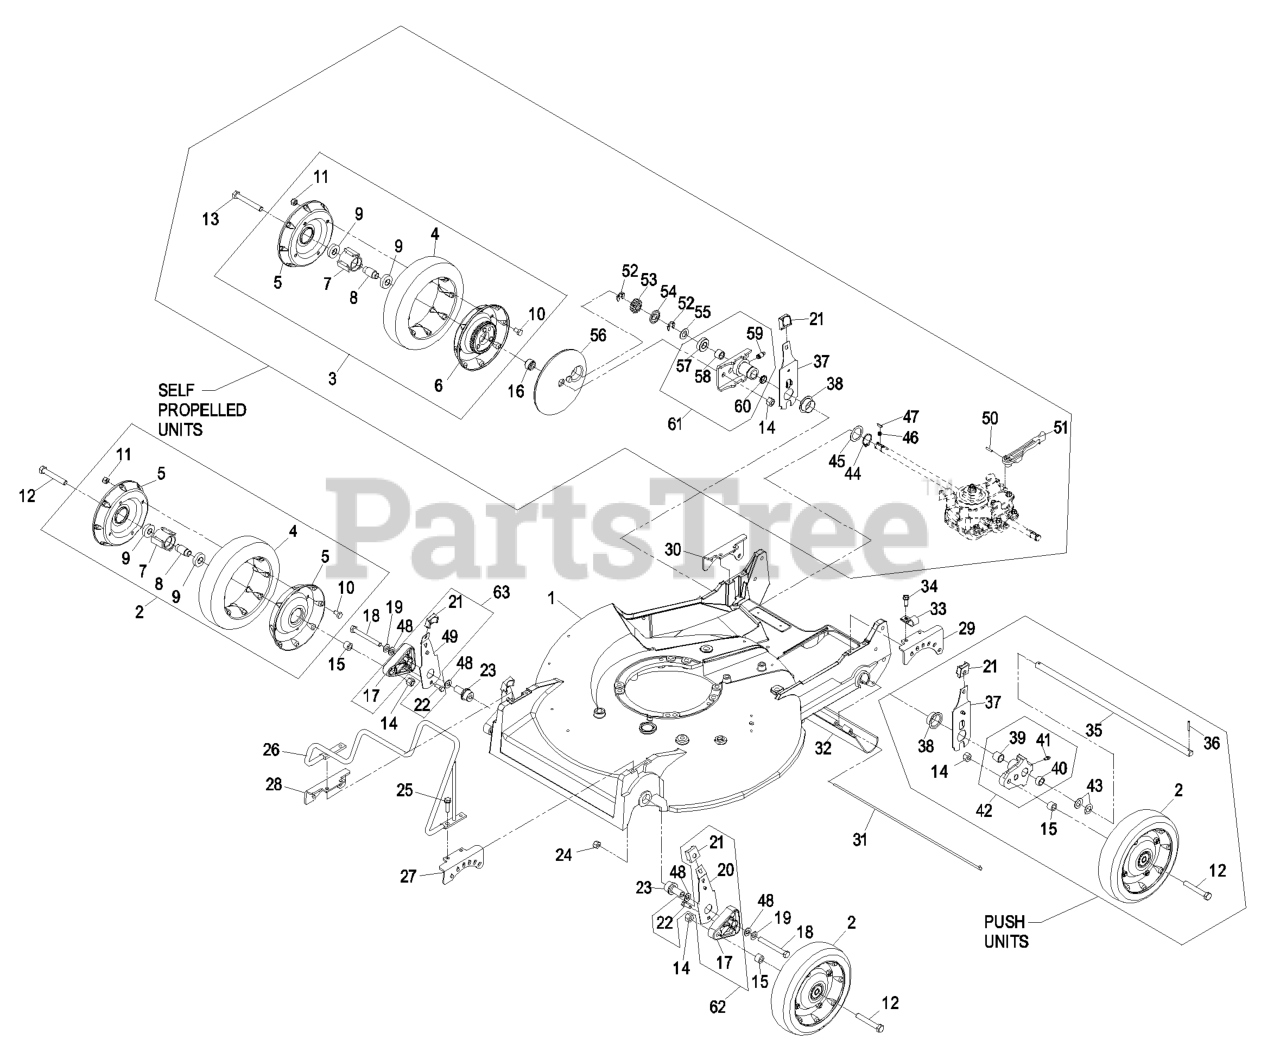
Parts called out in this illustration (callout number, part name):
7	HUB-BEARING
8	SPACER-BEARING
9	BEARING-WHEEL
10	SCREW-HH
11	NUT-LOCK, NI
12	BOLT-CARR
13	SCREW-HH
14	NUT-LOCK, CONE
15	SPACER-WHEEL
16	SPACER-COVER, WHEEL
17	ARM-PIVOT, FRONT
18	SCREW-HH
19	WASHER-FLAT
20	LH FRONT SPRING ARM ASM
21	KNOB-ARM
22	SCREW-HWHTF
23	BUSHING-PIVOT, WHEEL
24	NUT-LOCK, NI
25	SCREW-HWHTF
26	GUARD-ENGINE
27	BRACKET,QUADRANT FRONT LH
28	BRACKET,QUADRANT FRONT RH
29	BRACKET,QUADRANT REAR LH
30	BRACKET,QUADRANT REAR RH
31	ROD-SHIELD
32	SHIELD-TRAILING
33	CLIP-LOOM
34	SCREW-HWHTF
35	SHAFT-AXLE, REAR
36	PIN-SPIROL
37	REAR SPRING ARM ASM
38	CAP-END
39	BUSHING
40	BUSHING
41	FITTING-GREASE
42	PIVOT ARM ASM
43	WASHER-PLAIN
44	RING-RETAINING
45	WASHER
46	SPRING-COMPRESSION
47	KEY
48	WASHER-THRUST, NYLON
50	PIN-SPRING
51	LEVER-SHIFT
52	RING-RETAINING
53	GEAR-PINION
54	WASHER-THRUST, OUTER
55	WASHER-THRUST, OUTER
56	COVER-WHEEL
57	BEARING-WHEEL
59	ZERK
60	SEAL-OIL
61	PIVOT ARM ASM
62	ASM, ARM FRNT WHL LH
63	ASM, ARM FRNT WHL RH
